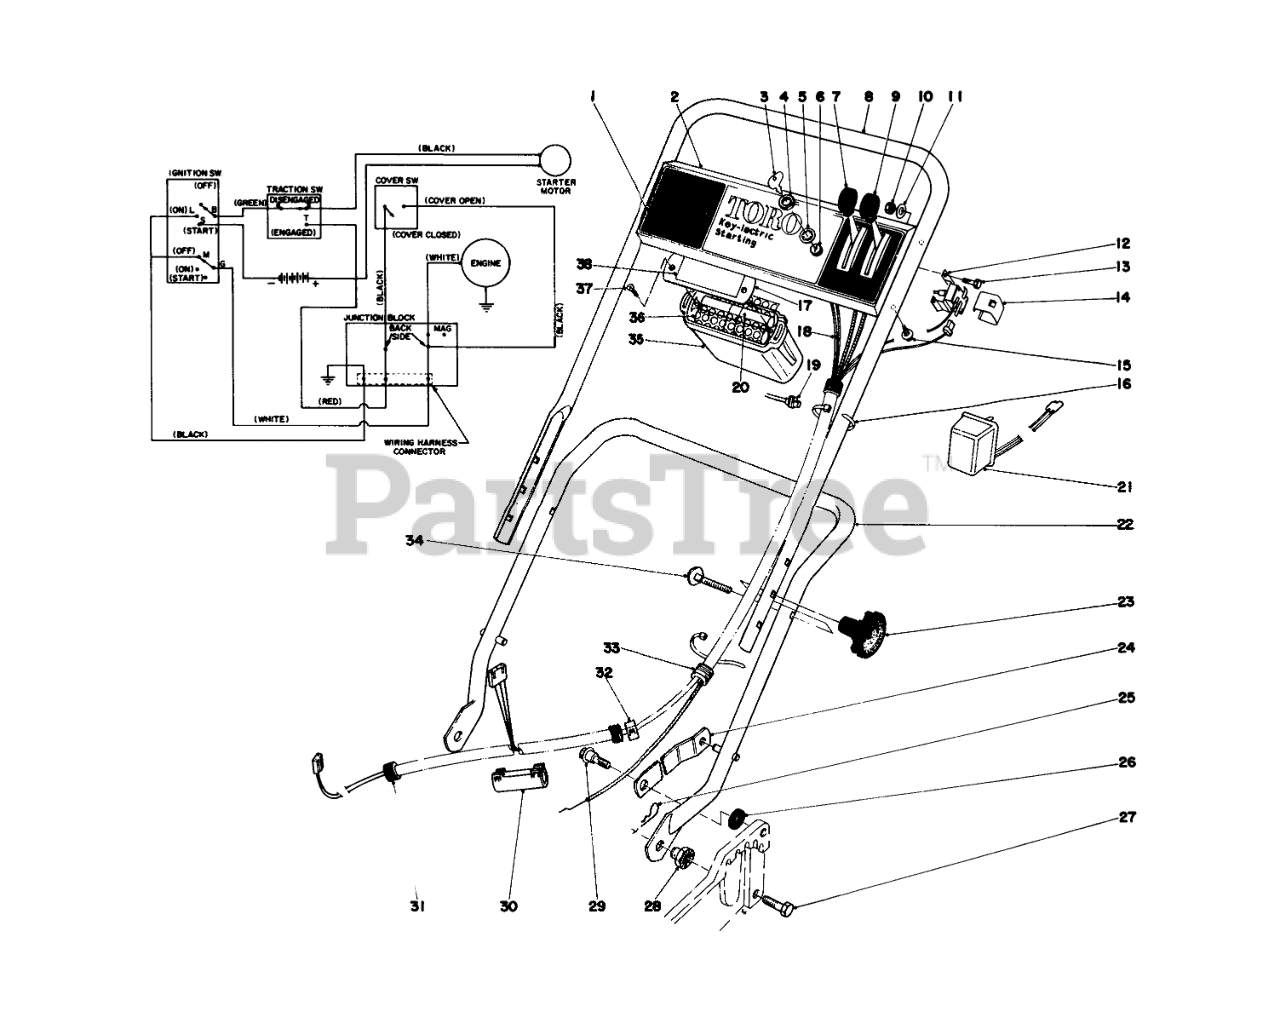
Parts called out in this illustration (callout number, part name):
1	Decal Control Plate
2	Control Plate
3	Key
5	WASHER-TOOTH, INTERNAL
6	SWITCH-STARTER
7	Throttle Control
8	Upper Handle
9	Throttle Control
10	NUT-HEX
11	WASHER-FLAT
12	Safety Switch
13	SCREW-HH
14	Cover Switch
15	SCREW-HWHTF
16	TIE-CABLE
17	Cover
18	Wiring Harness
19	Plug & Wire
20	Battery Pack Assembly (Incl. Ref. #17, 19-20 & 35-38)
21	Charger
22	LOWER HANDLE ASM
24	HANDLE LATCH
25	PIN-COTTER, HAIR
26	SPACER
27	SCREW-HH
28	HANDLE PIVOT NUT
29	SCREW-SHOULDER
30	Breakout Fitting
31	WIRING HARNESS COVER
32	RING FITTING
33	Upper Wiring Harness
34	HANDLE SCREW
35	Container Pack
36	Spacer
38	Decal-Battery
